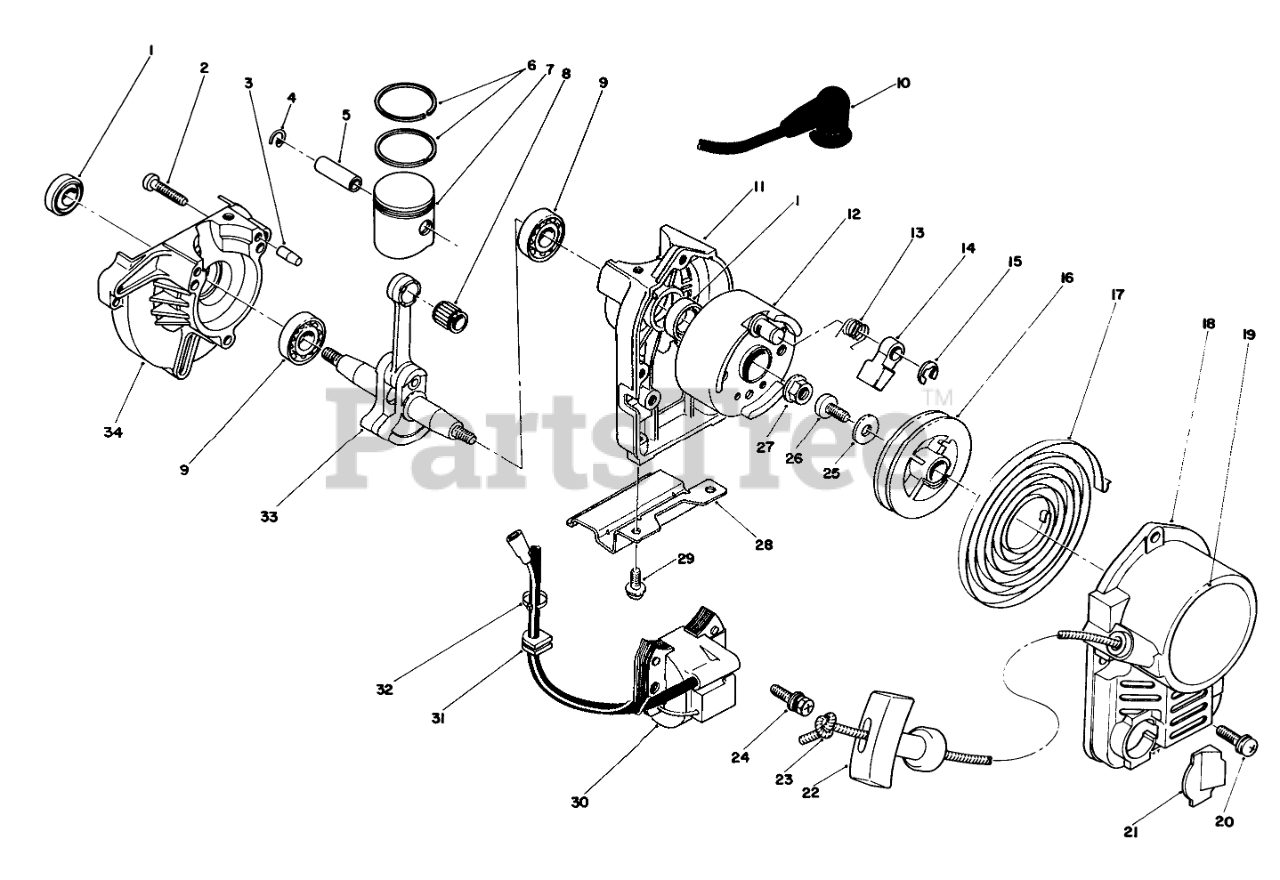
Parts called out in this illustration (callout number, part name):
1	OIL SEAL
2	Screw
4	PISTON PIN CLIP
5	Pin-Piston
6	TOP RING
7	Piston
8	NEEDLE BEARING
9	BEARING
10	CAP-PLUG
11	STARTER CASE
12	Rotor
13	Spring-Return
14	RATCHET
15	SNAP RING
17	SPRING
18	Case-Starter
19	RECOIL COVER DECAL
20	SCREW & WASHER
21	Grommet
22	Knob-Starter
23	Rope-Recoil
24	Bolt & Washer
25	Washer
26	SCREW
28	STAND
29	SCREW & WASHER
30	IGNITION COIL
31	GROMMET
33	CRANKSHAFT ASM
34	DRIVE CASE
